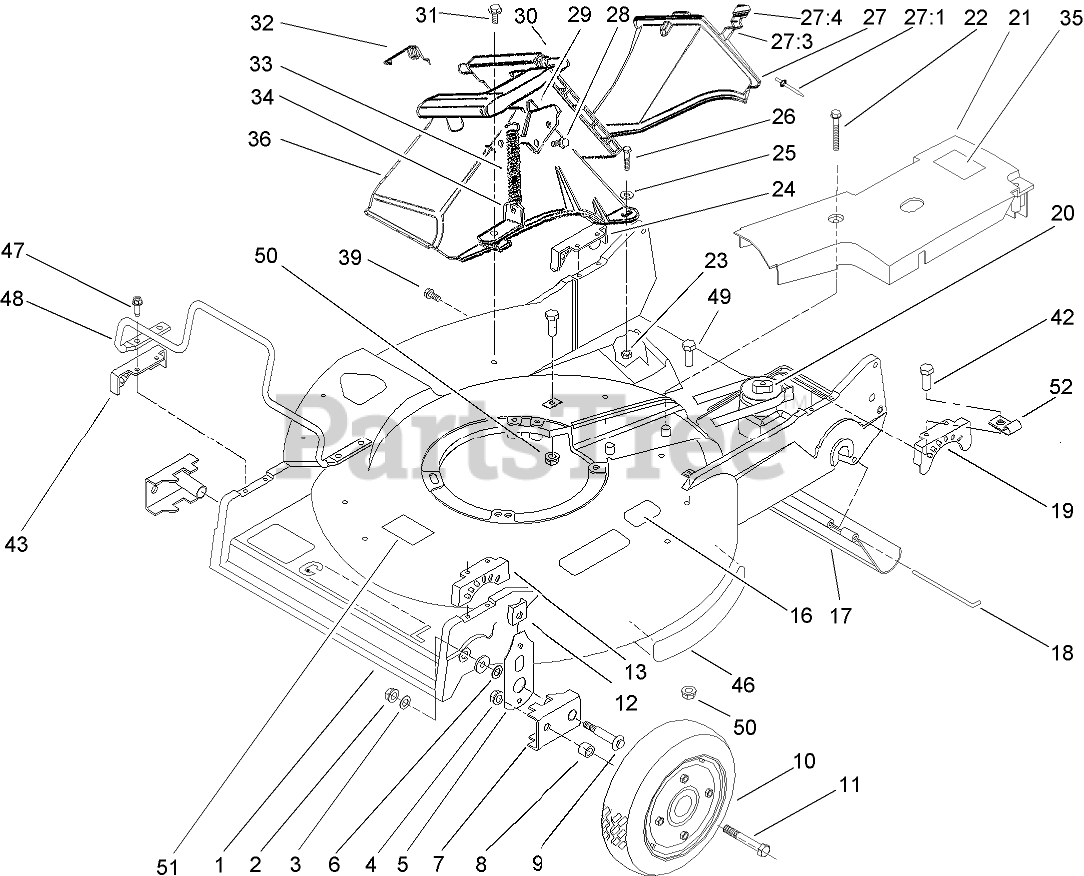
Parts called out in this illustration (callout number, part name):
1	HOUSING ASM
2	NUT-LOCK
3	WASHER
4	NUT-LOCK, CONE
5	FRONT SPRING ARM ASM
6	WASHER-THRUST
7	ARM-PIVOT, FRONT
8	SPACER-WHEEL
9	BOLT-WHEEL
10	Wheel and Tire ASM
11	SCREW-HH
12	KNOB-ARM
13	QUADRANT-FRONT, LH
16	DECAL-STD, SAFETY
17	SHIELD-TRAILING
18	ROD-SHIELD
19	QUADRANT-REAR, LH
20	GEAR CASE ASM
21	COVER-BELT
22	SCREW-HHFTF
23	NUT-LOCK, NI
24	QUADRANT-REAR, RH
25	WASHER-FLAT
26	SCREW-HH
27	DISCHARGE PLUG ASM
27:1	RIVET-HEAD, FLAT
27:3	LATCH-PLUG, DISCHARGE
27:4	GRIP-LATCH
28	SCREW-PLASTITE
29	LATCH-PLATE
30	DISCHARGE DOOR ASM
31	SCREW-HWH
32	RETAINER-DOOR
33	SPRING-DOOR
34	BRACKET-SPRING
35	LABEL-GREASE
36	TUNNEL-DISCHARGE
39	SCREW AND WASHER ASM
42	SCREW-HWHTF
43	QUADRANT-FRONT, RH
47	SCREW-HWHTF
48	GUARD-ENGINE
49	SCREW-HH
50	NUT-LOCK, NI
51	DECAL-BLADE
52	CLIP-CLOSED, INSULATED
